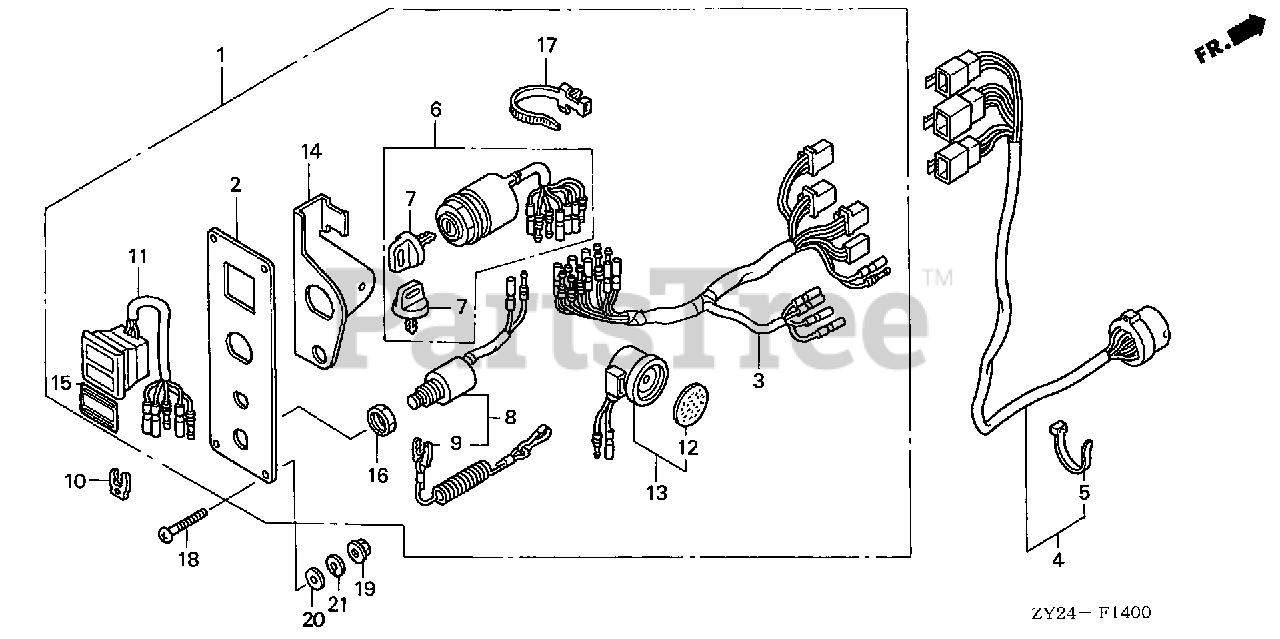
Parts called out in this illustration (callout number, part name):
1	PANEL ASSY., CONTROL (2-LED)
2	PANEL, CONTROL
3	HARNESS ASSY., SWITCH PANEL
4	CABLE ASSY., SWITCH PANEL
5	TIE, CABLE (2.4X92) (NATURAL)
6	SWITCH ASSY., COMBINATION
7	KEY ASSY., COMBINATION SWITCH (35100-ZV5-003 ONLY)
8	SWITCH ASSY., EMERGENCY STOP
9	WIRE, EMERGENCY
10	CLIP, EMERGENCY LOCK
11	LAMP ASSY., INDICATION (2-LED)
12	PLATE, TURN SIGNAL BUZZER
13	BUZZER, WARNING
14	BRACKET, BUZZER
15	MARK, SWITCH PANEL
16	NUT, HEX. (16MM)
17	BAND, WIRE HARNESS (150MM) (NATURAL)
18	SCREW, PAN (5X40)
19	NUT, FLANGE (5MM)
20	WASHER, PLAIN (5MM)
21	WASHER, SPRING (5MM)
